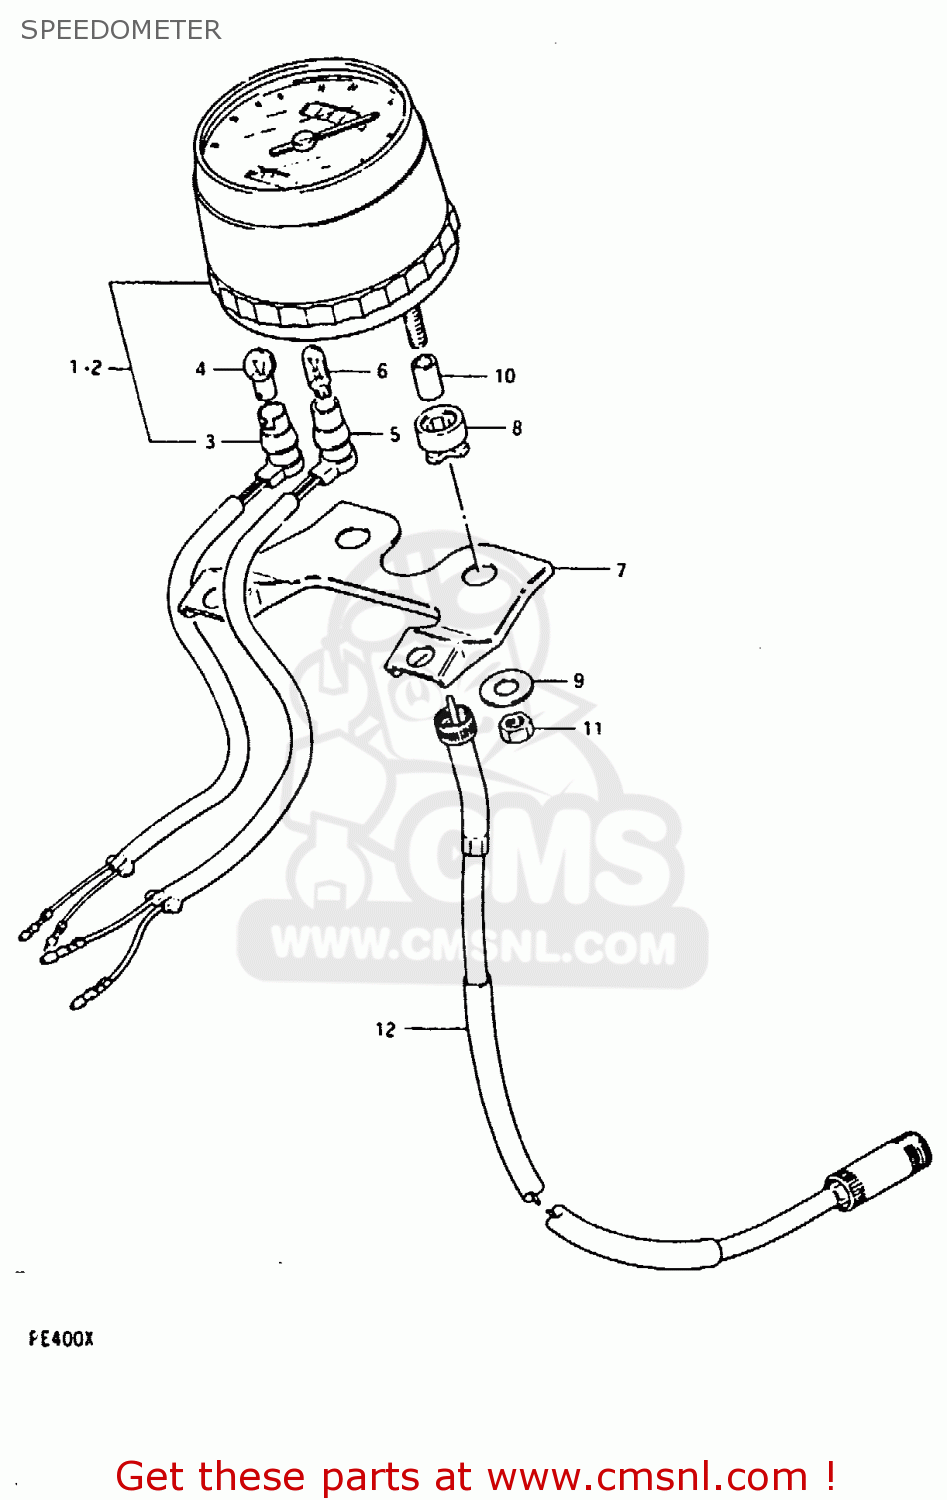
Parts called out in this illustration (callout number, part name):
2	SPEEDOMETER ASSEMBLY
3	SOCKET,METER
4	BULB(6V1.7W,STANLEY,A61A)
5	SOCKET,METER
6	BULB(6V1.7W,STANLEY,A61A)
7	BRACKET,SPEEDOMETER
8	CUSHION,SPEEDOMETER
9	WASHER
10	SPACER,METER
11	NUT
12	CABLE ASSEMBLY,SPEEDOMETER
